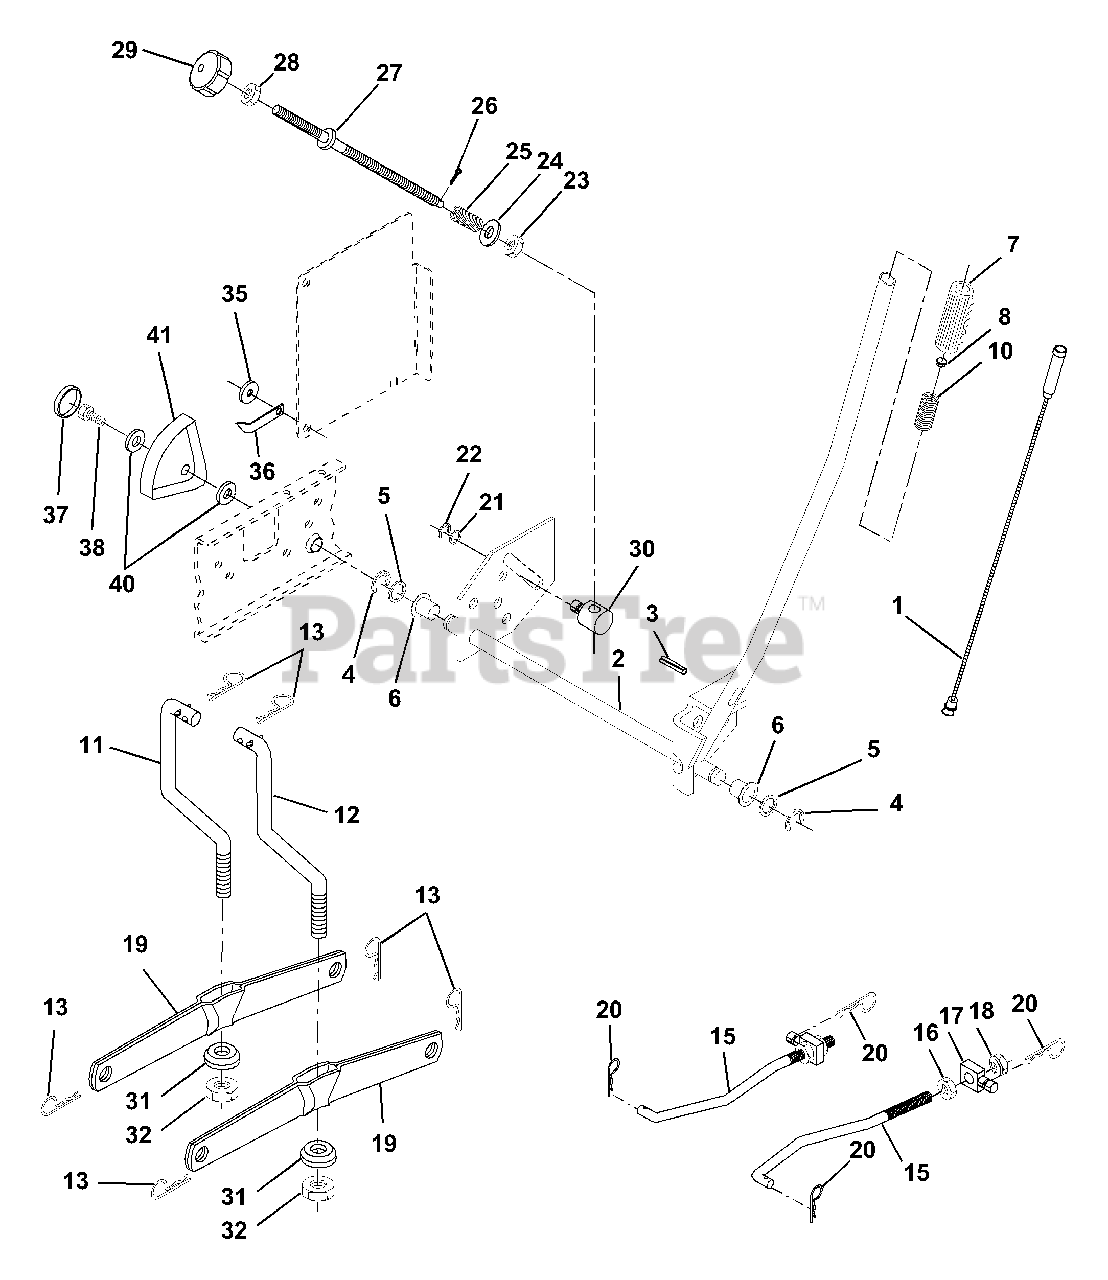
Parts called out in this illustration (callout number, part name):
1	Wire Asm Inner W/plunger 20 56
2	Shaft Asm Lift RH w/Inf W/T
3	Pin Groove 1 500 Zinc
4	E Ring #5133-62
5	Washer 21/32 X 1 X 21 Ga
6	Bearing Nylon Blk 629 Id
7	Grip Handle Fluted Blk
8	Button Plunger Black
10	Spring Cprsn 3 750 Oiled
11	Link Lift LH Fixed Length
12	Link Lift RH Fixed Length
13	Retainer Spring
15	Link Front
16	Nut Jam Hex 1/2-13 Unc
17	Trunnion Blk Zinc
18	Nut Lock W/wsh 1/2-13unc
19	Arm Suspension Rear
20	Retainer Spring
21	Washer 15/32 X 3/4 X 16 Ga
22	Ring Klip #t5304-37
23	Nut Special
24	Washer 13/32 X 5/8 X 16 Ga
25	Spring Compression
26	Pin Cotter 3/32 X 1/2
27	Rod Adj Lift Zinc 9 75 Wrk Lg
28	Nut Hex Jam 3/8-16 Unc
29	Knob Inf 3/8-16 Unc Blk W/sym
30	Trunnion Dp Stop Dbl Thds PLT
31	Bearing Pvt Lift Spherical
32	Nut Crownlock 3/8-24
35	Washer Nylon .44 x .75 x .032
36	Pointer Pnt Height ind .505
37	Plug Hole Blk 1.485/1.515 Dia.
38	Screw Thdrol 5/16-18 x 3/4
40	Washer 11/32 x 1-1/2 10 Ga.
41	Scale Ind. Height Blk.
